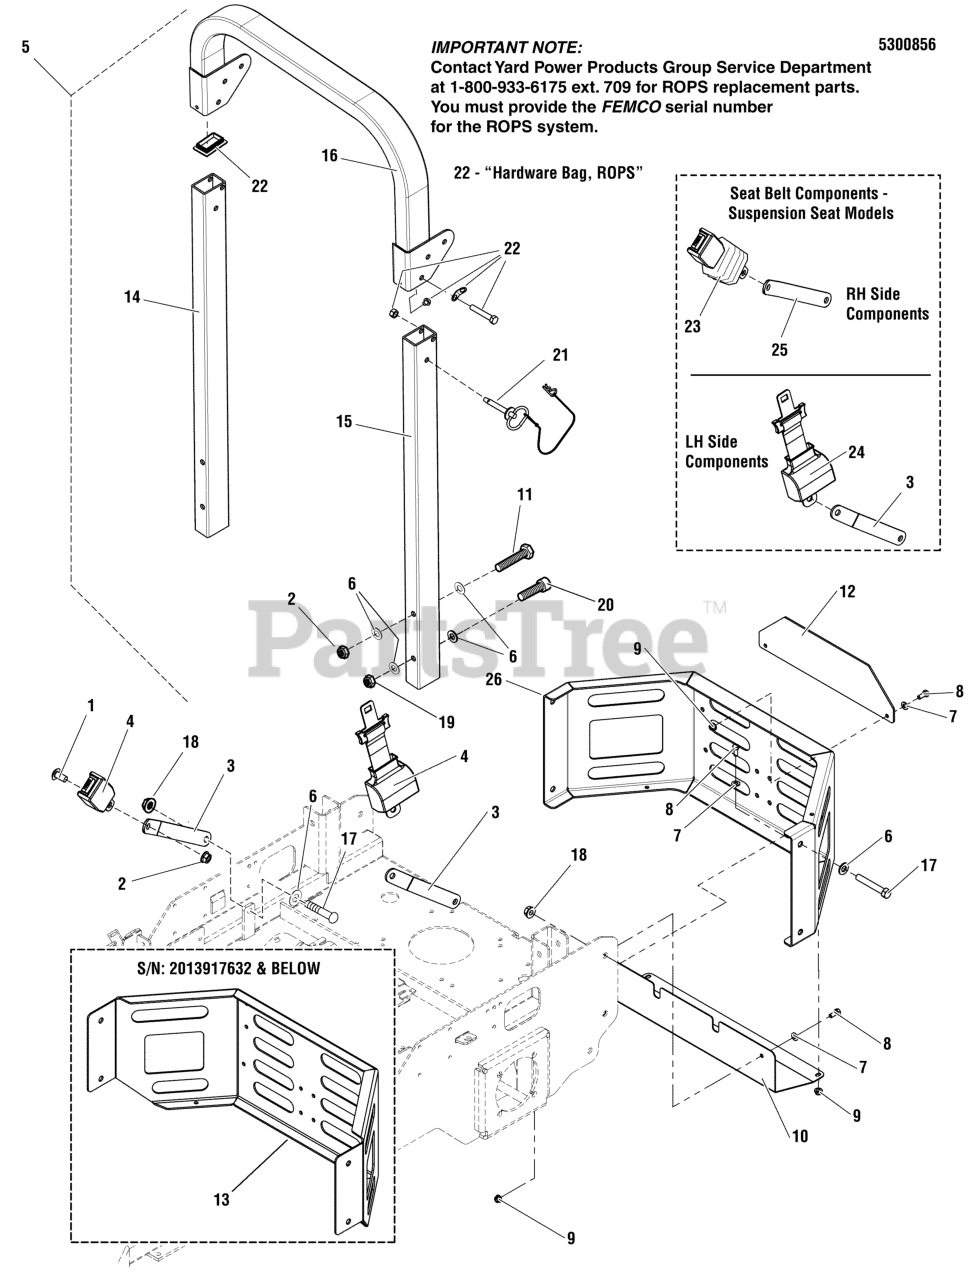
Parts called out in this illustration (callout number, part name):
1	SCREW, 1/2-13 X 1.00, SHCS
2	NUT, Hex Flange, Nylock, 1/2-13
3	PLATE, SEAT BELT EXTENSION - RED
4	SEAT BELT, RETRACTING - ASSM
5	*BOLT
6	WASHER, 1/2 SAE
7	WASHER, 5/16" SAE
8	BOLT, 5/16-18 X 3/4 GD5
9	NUT, 5/16-18 HEX NYLOCK FLANGE
10	PLATE, HEAT SHIELD - RED
11	BOLT, 1/2-13 X 3-1/4, HEX HD, GD5, CZ (SV)
12	PLATE, REAR BUMPER, 61 SNP - SNP RED
13	KIT, BUMPER, S200
14	ROLL BAR POST, RH (SV)
15	ROLL BAR POST, LH (SV)
16	ROLL BAR TOP LOOP (SV)
17	BOLT, 1/2-13 X 1-1/4 GD5 CZ
18	NUT, 1/2-13 HEX NYLON LOCK
19	NUT, 1/2-13 HEX NYLON LOCK
20	BOLT, 1/2-13 X 3-1/2, HEX HD, GD5, CZ (SV)
21	PIN, HITCH, .50 X 3.25 W/ LANYARD (SV)
22	HARDWARE BAG, ROPS S200X
23	SEAT BELT ASSM, RETRACTOR + SUP SLEEVE
24	ORDER P/N 5105137 (CONTAINS BOTH SEAT BELT RETRACTOR + SUPER SLEEVE BUCKLE)
25	PLATE, SEAT BELT EXTENSION - RED
26	WELD, REAR BUMPER, SNP PRO 61
